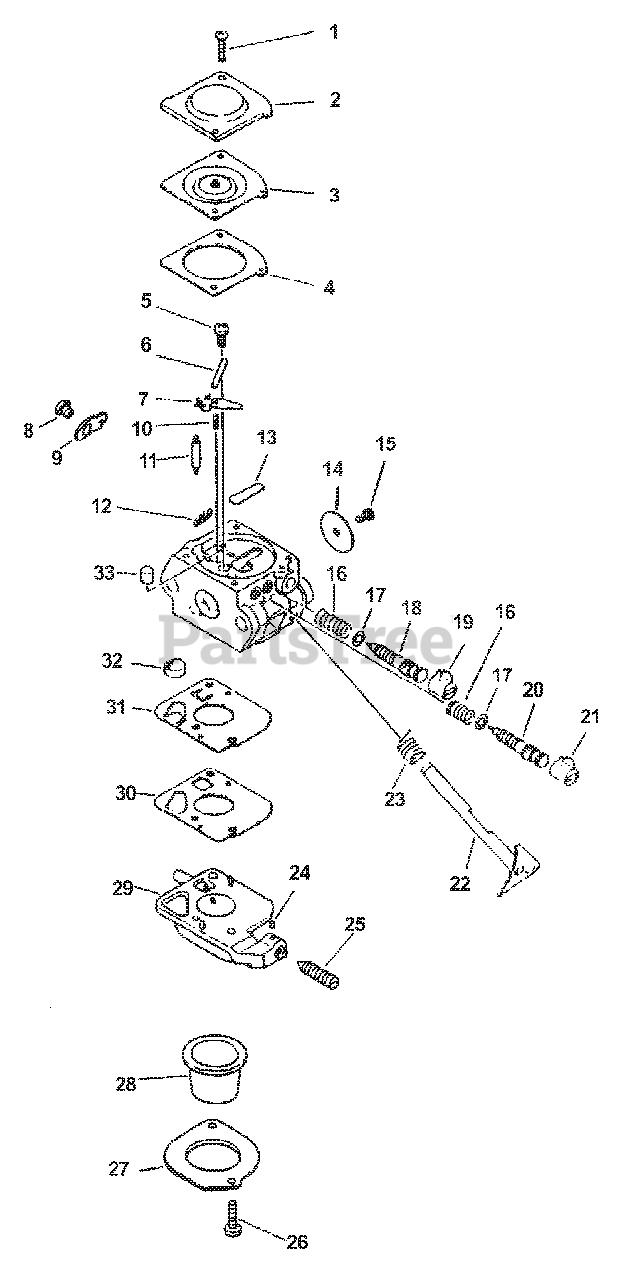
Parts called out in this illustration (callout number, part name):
2	COVER, METERING
3	DIAPHRAGM
4	GASKET, DIAPHRAGM
5	SCREW, METERING LEVER PIN
6	PIN, METERING LEVER
7	LEVER, METERING
9	LEVER, THROTTLE
10	SPRING, METERING LEVER
11	VALVE, INLET NEEDLE
12	RING, RETAINING
13	PLUG, WELCH
14	VALVE, THROTTLE
18	NEEDLE - LOW SPEED
19	CAP, LIMITER
20	NEEDLE - HIGH SPEED
21	CAP, LIMITER
22	SHAFT, THROTTLE
23	SPRING, TRIGGER
24	PIECE, FRICTION
25	SCREW, IDLE ADJUST
26	SCREW, RETAINER
27	RETAINER, PURGE BULB
28	BULB, PURGE
29	BASE, PURGE
30	GASKET, PUMP
31	DIAPHRAGM, PUMP
32	STRAINER
33	NOZZLE, CHECK VALVE
